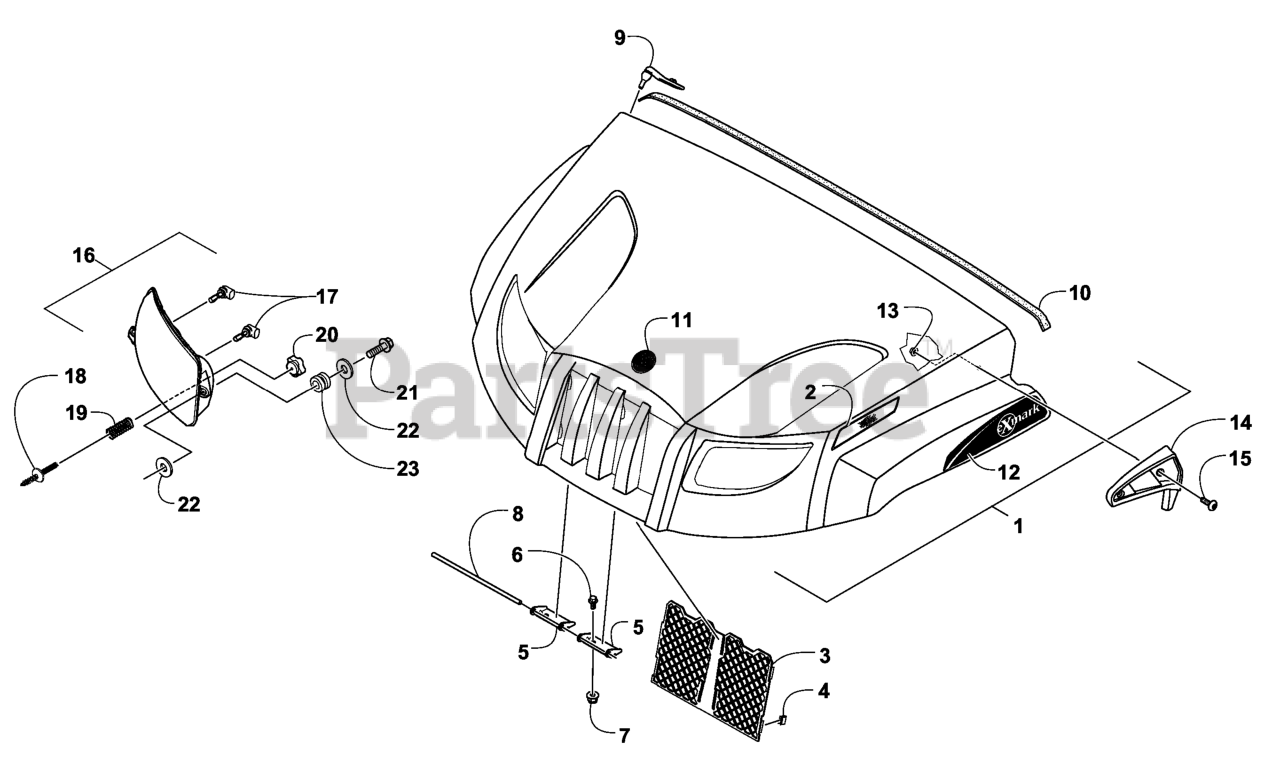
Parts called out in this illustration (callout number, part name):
2	REFLECTOR-FRONT, RH
2	REFLECTOR-FRONT, LH
3	GRILL-SCREEN
4	CLIP-U TYPE
5	BRACKET-HOOD HINGE
6	SCREW-HFH
7	NUT-HHF, LOCK, (NI)
8	PIN-HOOD
9	STRAP-HOLDDOWN, HOOD
10	SEAL-HOOD
11	DECAL-EXMARK
12	DECAL-BOX HOOD, RH
12	DECAL-BOX HOOD, LH
13	LINKAGE,LOWER CALIPER RH
14	LOUVER-HOOD, RH
14	LOUVER-HOOD, LH
15	SCREW-SHOULDER
16	HEADLIGHT-RH
17	BULB-HEADLIGHT
18	STUD-DOUBLE END
19	SPRING-ADJUSTMENT, HEADLI
20	KNOB-ADJUSTMENT
21	BELLCRANK ASM
22	WASHER-FLAT
23	GROMMET-GAUGE MOUNT
